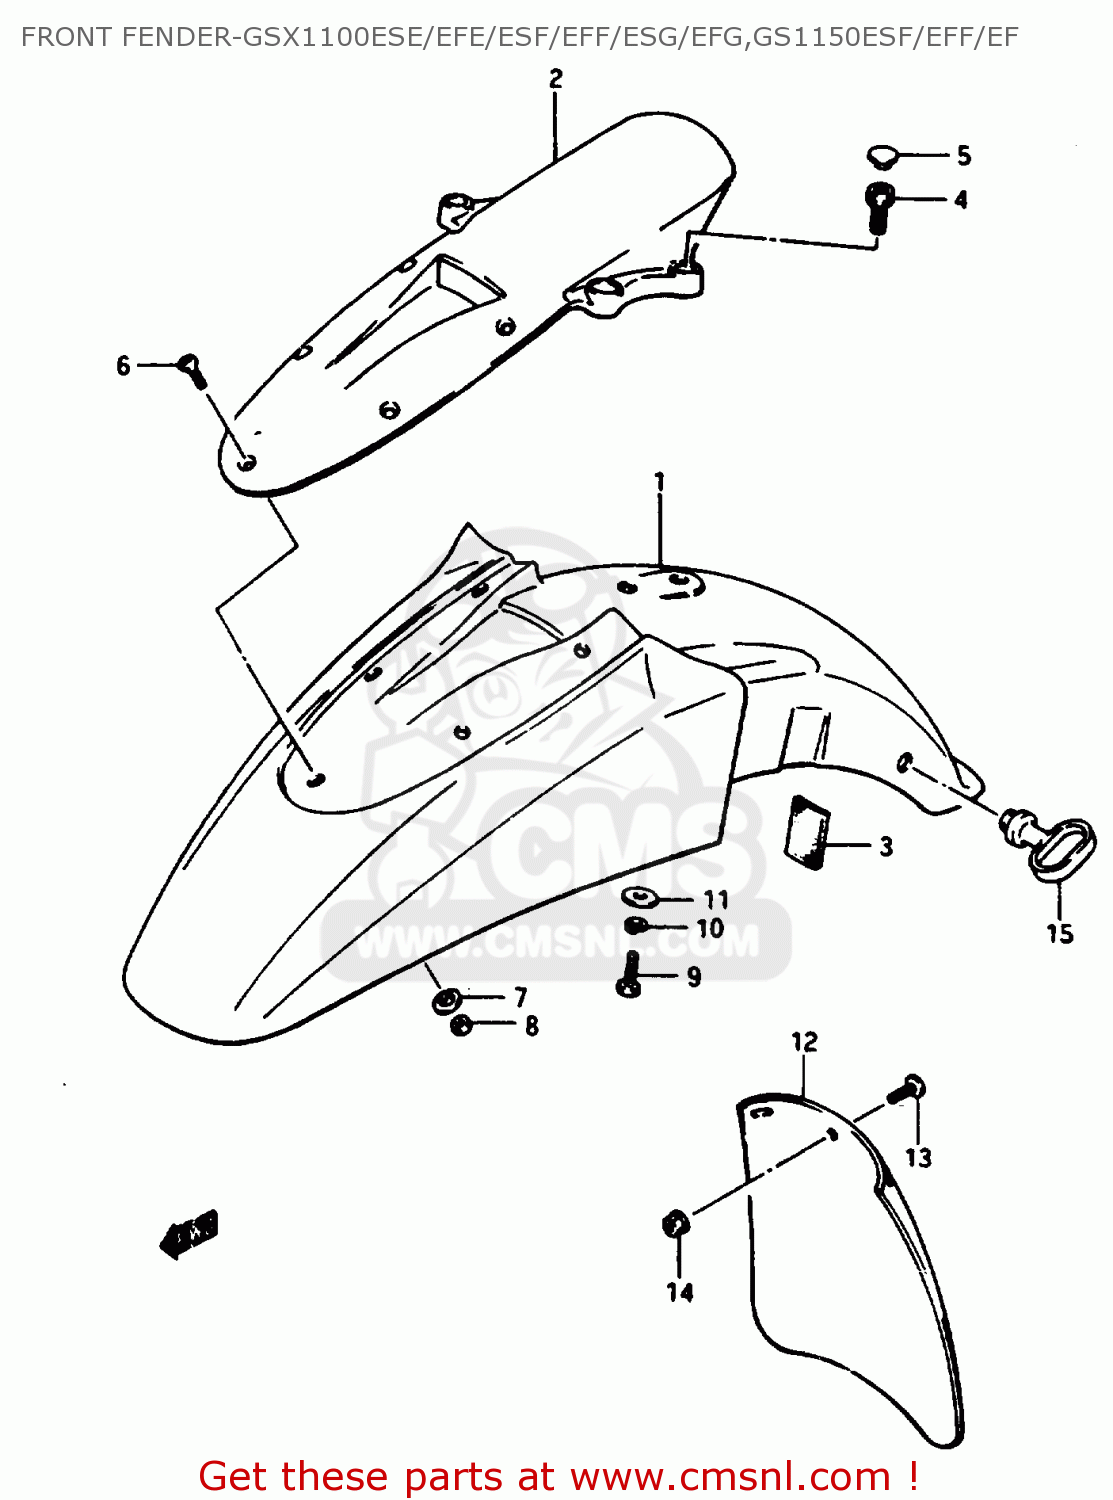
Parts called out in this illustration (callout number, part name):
1	FENDER,FRONT
2	BRACE,FR FENDER CTR
3	CUSHION
4	BOLT
5	CAP(OD:14.5)
6	SCREW, CENTER
7	WASHER
8	NUT 8MM
9	BOLT
10	WASHER,LOCK
11	WASHER
12	MUD FLAP,FRONT FENDER
13	SCREW 5X10
14	NUT
15	GUIDE,CABLE
